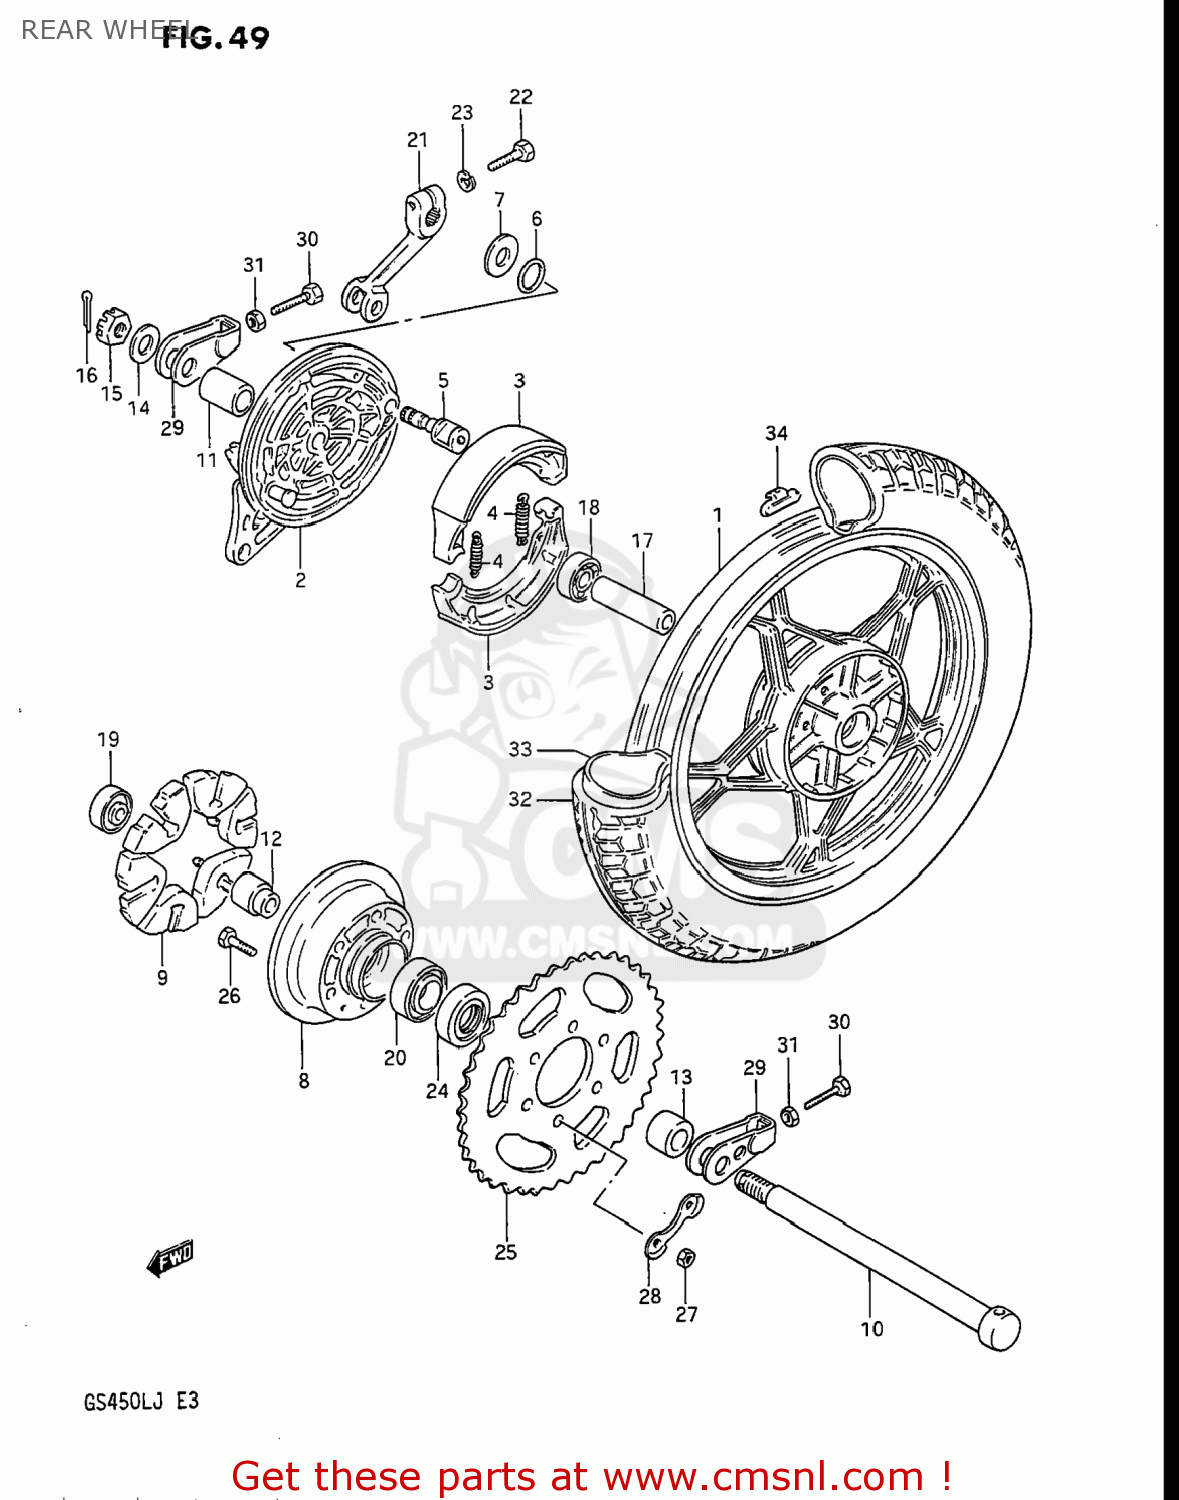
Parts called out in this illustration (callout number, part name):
1	CASTING WHEEL,REAR 2.15
2	PANEL,REAR HUB
3	SHOE,BRAKE
4	SPRING,BRAKE SHOE
5	CAM,FRONT BRAKE
6	O-RING,BOSS
7	WASHER (15X24X1.6)
8	DRUM,REAR SPROCKET MOUNT
9	ABSORBER,RR HUB SHOCK
10	AXLE,REAR
11	SPACER(17.5X28X44.8)
12	SPACER,REAR HUB BEARING
13	SPACER(17X30.5X22.3)
14	WASHER (17X30X3.2)
15	NUT
16	PIN,COTTER
17	SPACER (17.6X24X57)
18	BEARING
19	BEARING
20	BEARING
21	LEVER,REAR BRAKE CAM
22	BOLT
23	WASHER,LOCK
24	SEAL,OIL(30.5X52X8)
25	SPROCKET,RR
26	BOLT(10X35.5)
27	NUT
28	WASHER
29	ADJUSTER,CHAIN
30	BOLT 8X50
31	NUT
32	TIRE
33	TUBE ASSY,WHEEL,INNER 4.60-16
34	BALANCER,WHEEL
